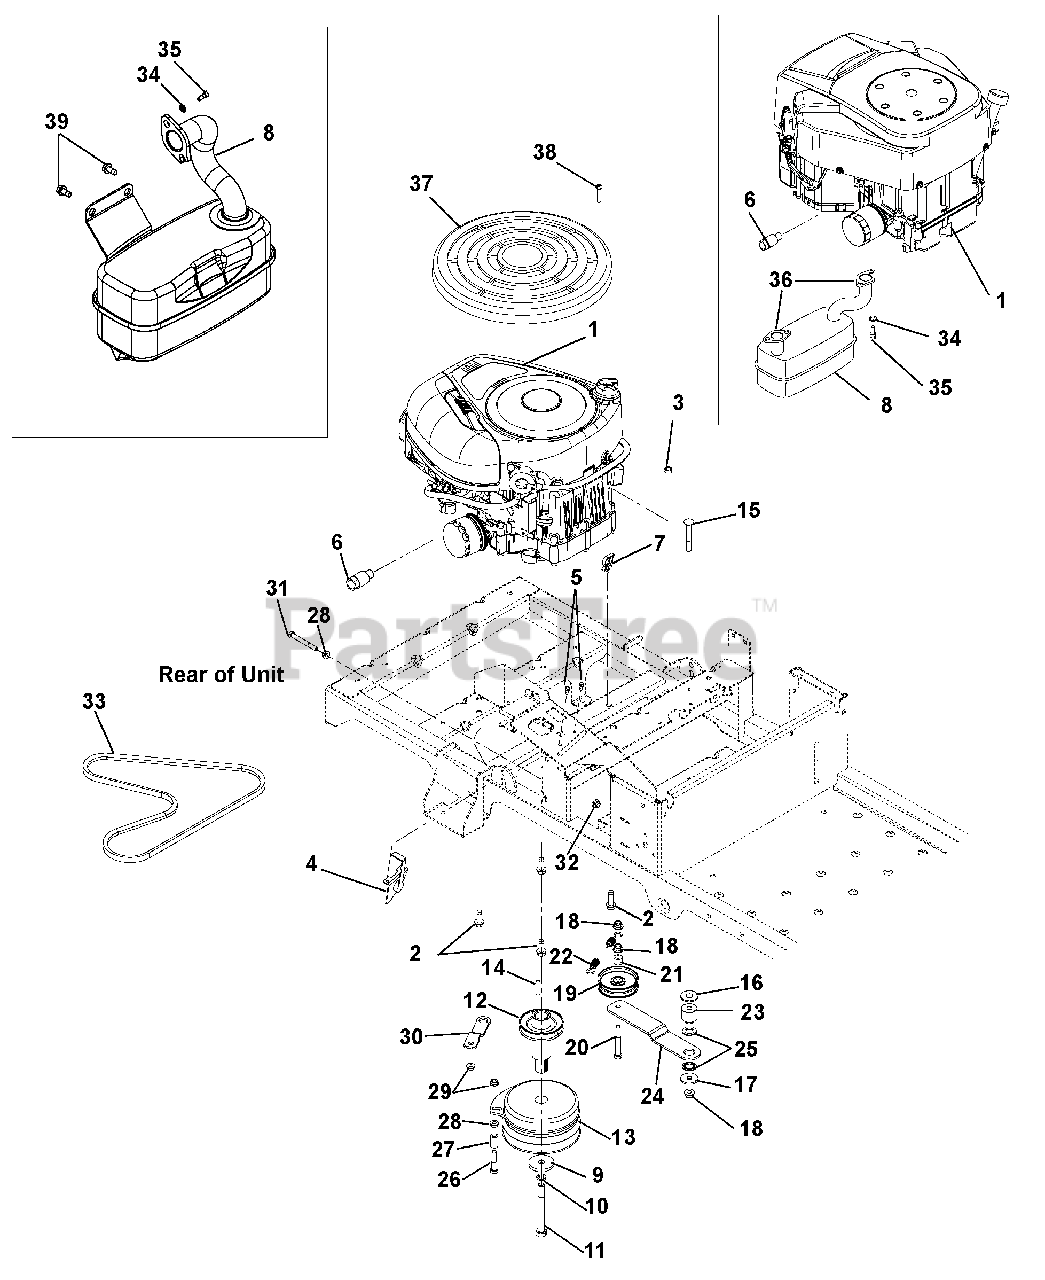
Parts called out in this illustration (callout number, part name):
1	ENGINE, B&S 14.5 POWERBUILT
1	ENGINE, KOHLER TWIN 20 HP
1	ENGINE, KOHLER TWIN - 22HP
2	@SCR-TAP .38-16X1.25 HWH TR YZ
3	@NUT-LK-CTR-JAM .375-16 YWZC
4	THROTTLE/CHOKE CABLE
4	CABLE, CHOKE/THROTTLE COMBO
5	@SCR-TAP 10-24X.50 HWH TR YWZC
6	DRAIN, OIL
7	WIRE CLIP
8	MUFFLER, KOHLER TWIN COURAGE
8	MUFFLER, B&S 500 BBZ
9	WSHR-FL-STL .469X2.00X.25 YWZC
10	@WSHR-LK .44X.109 REG YWZC
11	BLT-HEX .44-20X4.50 GR8 YWZC
12	WMT-PTO EXTENSION W/SHEAVE
13	CLUTCH, 105 FT*LB MONO POLE
14	KEY-SQ .25 X 1.25 X .25 SAE
15	@BLT-RDHDSQNK .38-16X2.75 G5YZ
16	@WSHR-FL-STL.563X1.38X.109YWZC
17	WSHR-FL-STL .406X1.375X.135 YZ
18	@NUT-LK-NYL-FLG .38-16 YWZC
19	PULLEY, ENGINE CLUTCH 03608
20	@BLT-HEX .38-16X2.75 GR5 YWZC
21	BSHG-SLV .391X.688X.52 PM
22	SPRING, EXTENSION
23	SPACER, GROUND DRIVE IDLER
24	IDLER ARM, GROUND DRIVE
25	BUSHING, IDLER ARM
26	SCR-CAP .31-18X1 3/4 S/HD YWZC
27	SPACER, RUBBER 5/16 IDX1.0 LG
28	@NUT-SPNLK-FLG .312-18 YWZC
29	@NUT-LK-TOP-FLG .31-18 YWZC
30	BRKT, CLUTCH STOP
31	@BLT-HEX .31-18X2.75 GR5 YWZC
32	@NUT-LK-NYL-FLG .31-18 YWZC
33	V-BELT, HA-RAW EDGE
34	@WSHR-LK .31X.078 REG YWZC
35	SCR-CAP .31-18X.75 S/HD
36	GASKET, MUFFLER COURAGE TWIN
37	GUARD, BRIGGS ENGINE (SINGLE)
38	SCREW, 8-16X.87 PHPAN 3 LOBE
39	SCR-TAP .25-20X.50 HWH TR YWZ
